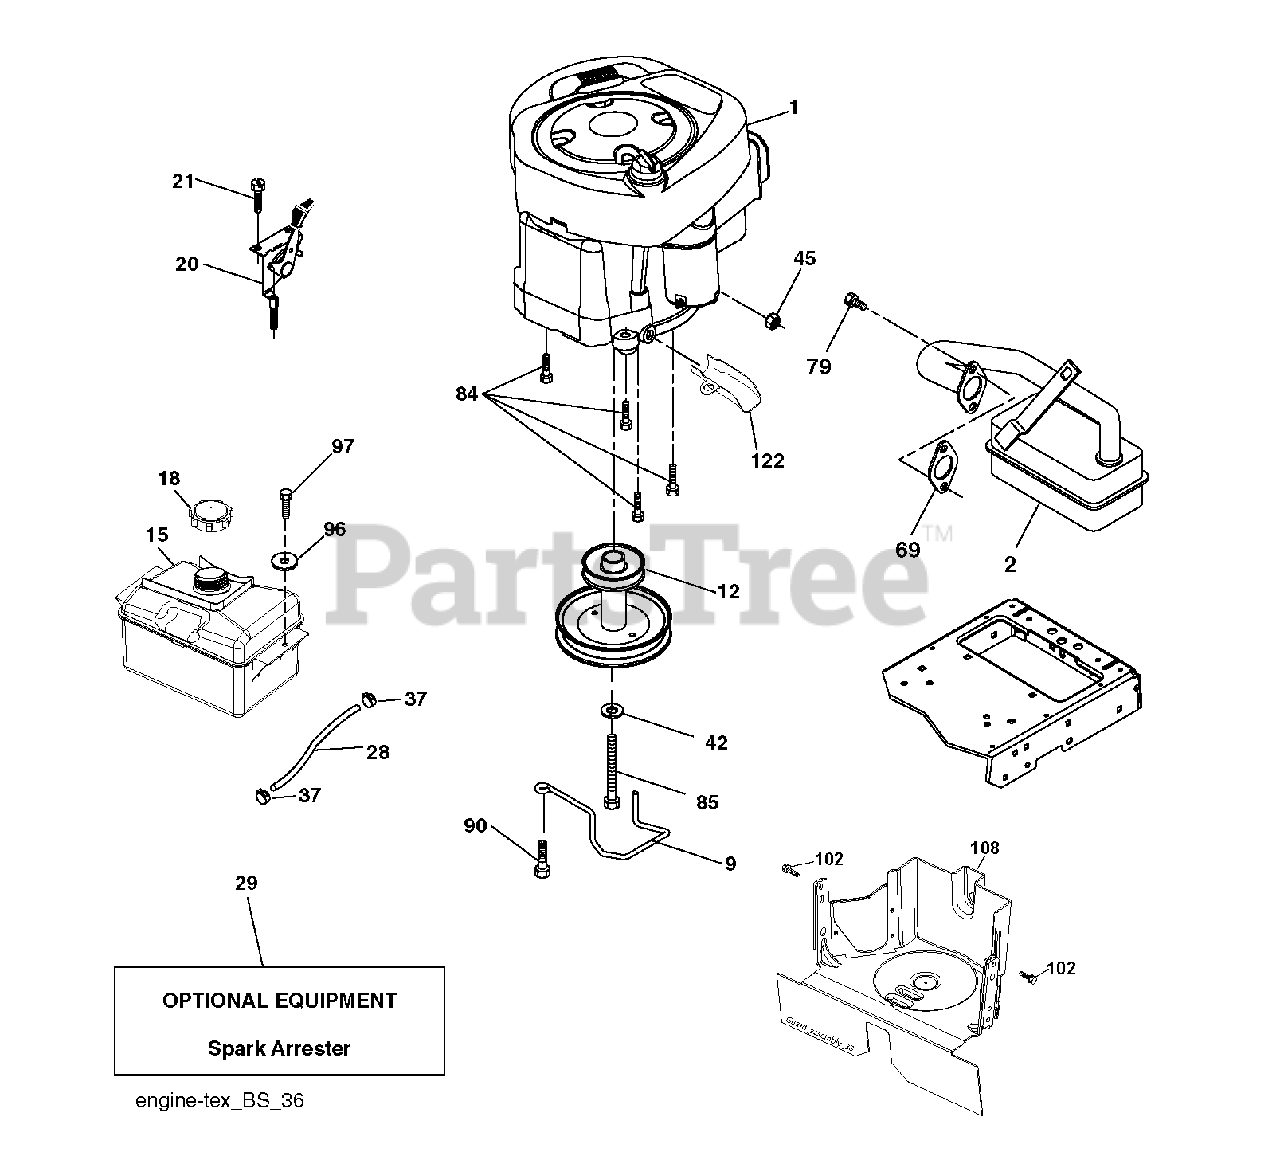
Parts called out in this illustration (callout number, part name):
9	KEEPER.BELT.ENGINE.3.25
12	PULLEY ENGINE
15	TANK FUEL FRT 1.5 GAL
18	CAP ASM.FUEL.2.25"FR.
20	CONTROL.TH/CK.C.
21	SCREW.#10 X 0.750.BOS THREAD
29	ARRESTER SPARK (OPTIONAL)
42	LOCKWASHER
45	NUT
69	REPL BY 532 27 22-93
79	SCREW.SOCKET HD.5/16-1
85	BOLT HEX 7/16-20X4-1/4"
90	SCREW 3/8-16X1
97	SCREW HEXWSHR 1/4-20X3/4
102	SCREW
108	Pulley Cover
122	EXTENSION DRAIN OIL
